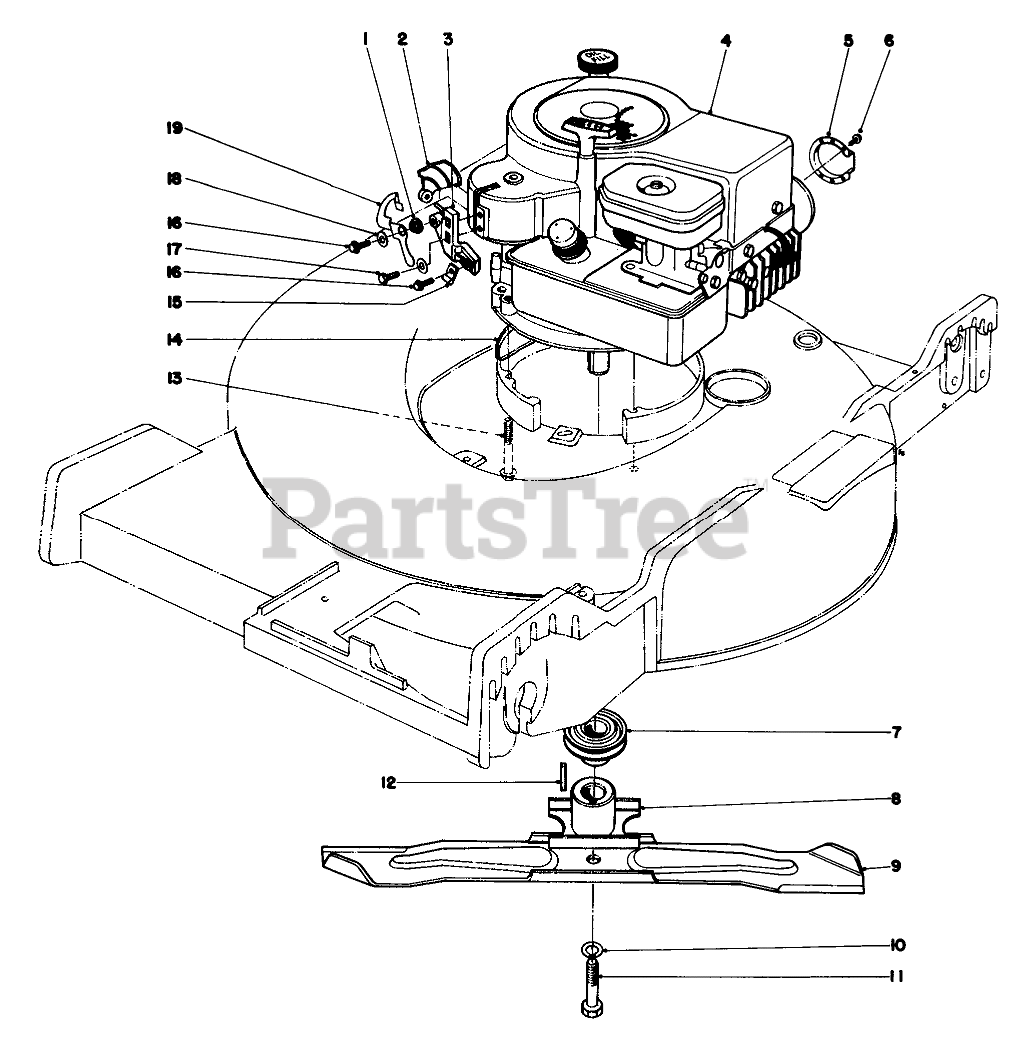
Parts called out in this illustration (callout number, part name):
1	BUSHING
2	INTERLOCK LEVER
3	CABLE & PIVOT BLOCK
4	Engine
5	Deflector
6	SCREW W/ENGINE
7	DRIVER PULLEY
8	BLADE RETAINER WA(BLACK)
9	Blade
10	WASHER-LOCK
11	BLADE SCREW
12	KEY-SQUARE
13	3/8-16 X 2-3/4 CAPSCR
14	HOUSING CAP
15	CLAMP
16	Screw
17	SCREW-SHWH
18	WASHER-FLAT
19	CAM INTERLOCK
